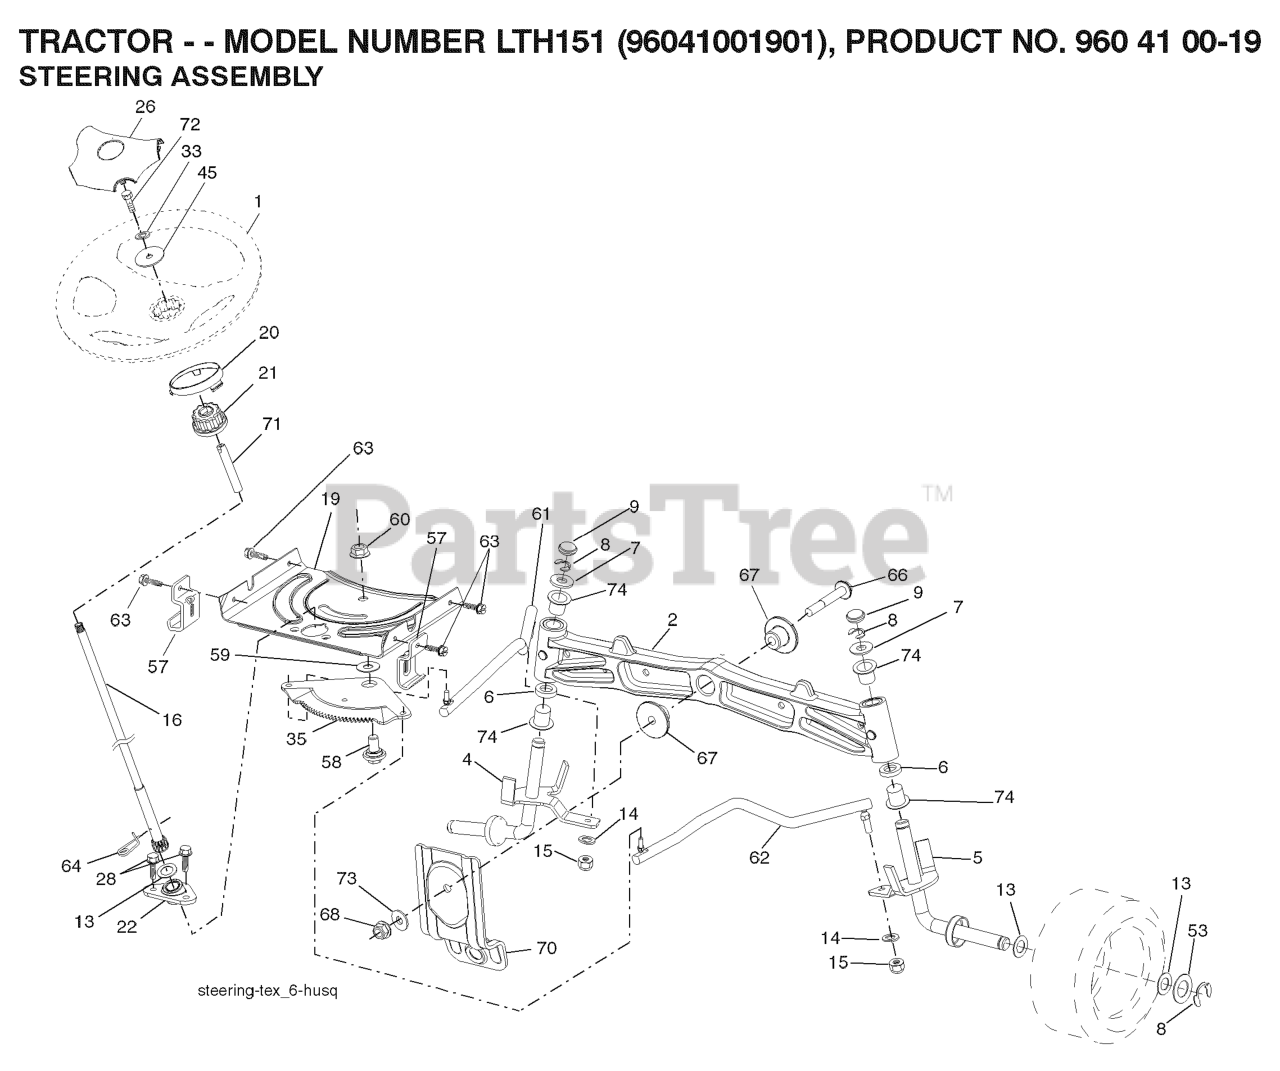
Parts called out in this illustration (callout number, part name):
1	STEERING WHEEL
2	AXLE.HALF.ASM.WELDED
4	SPINDLE.WELDED.LH.15"TEX
5	SPINDLE.WELDED.RH.15"T
6	THRUST WASHER
9	CAP.SPINDLE.BLACK
14	WASHER, LOCK 3/8
15	NUT CROWNLOCK 3/8-24
16	SHAFT STEERING
19	PLATE.STEER.DDL.NLT/NG
20	BOOT, STEERING
21	ADAPTER, WHEEL STNG..
22	BUSHING.ASM.STEERING.A
26	INSERT.CAP.STRG.WH.GRAY
28	SCREW, 3/8-16X3/4
33	WASHER.LOCK.HVY.HLCL.SPR.5/16
35	GEAR.SECTOR.PLATE.DDL.
45	WASHER.11/32
53	WASHER.HARDENED
57	BRACKET.UPSTOP.TEX
58	BOLT.SHOULDER.SECTOR.P
59	WASHER.THURST.SECTOR.S
60	NUT FLANGE LOCK 5/8-11
61	DRAGLINK.LH.BALLSTUD.D
62	DRAGLINK.RH.BALLSTUD.D
63	SCREW
64	RETAINER.CLIP.SPRING.S
66	BOLT HEX FGHD 7/16-14 X 3 SERR
67	BUSHING.PM.FRONT AXLE
68	NUT.LOCK.FLANGE.7/16
70	BRKT.DECK.SUSPENSION.F
71	SHAFT EXTENSION STEERING
72	BOLT YT
73	WASHER.1.5X.505X.118
74	BRNG T
